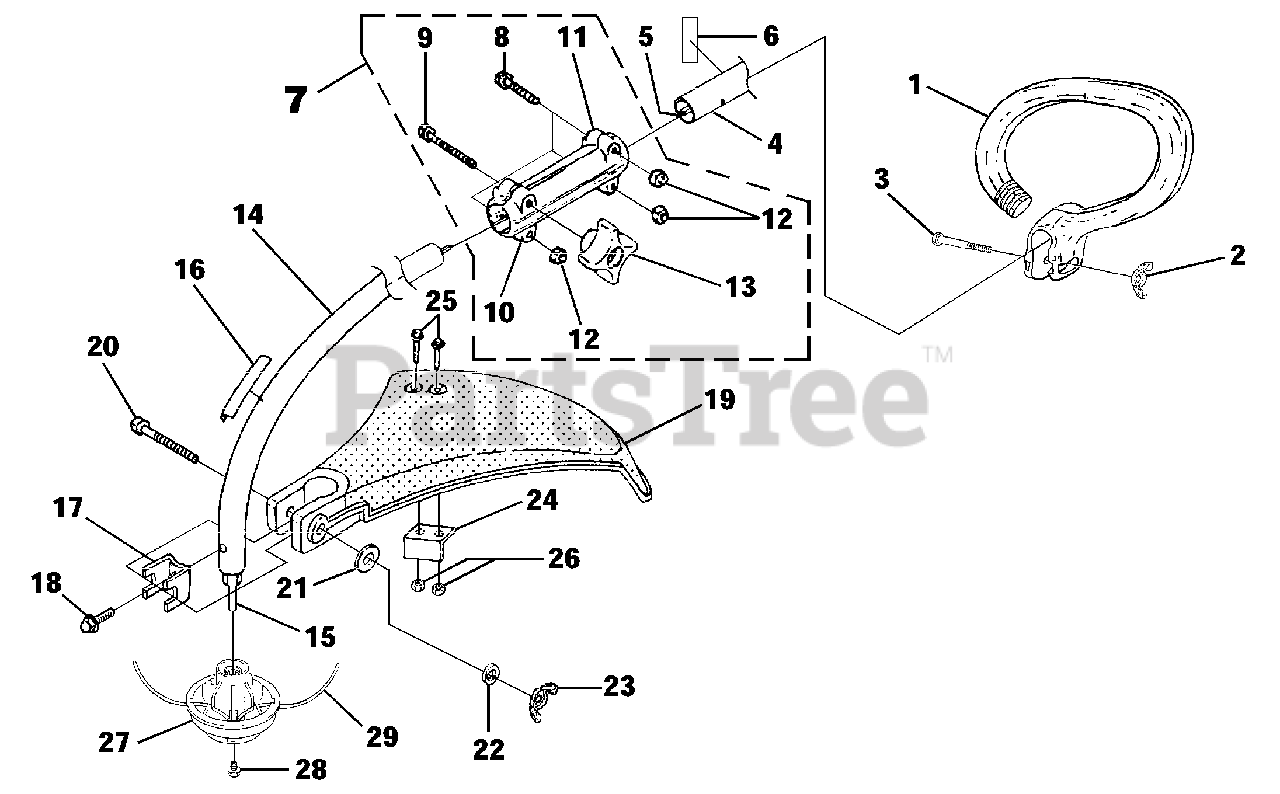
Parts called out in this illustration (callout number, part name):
1	HANDLE-Anti-Vibe
2	NUT-Wing, Washer Faced (1/4-20)
3	SCREW-Cap Hex Hd. (1/4-20 x 2")
4	DRIVESHAFT ASSY. (Upper)
5	FLEXSHAFT w/Collar & Liner
6	DECAL-Warning
7	COUPLER ASSEMBLY
8	SCREW-Hex Hd. (1/4-20 x 1 1/2")
9	SCREW-Cap Hex (1/4-20 x 2")
10	COUPLER (L.H.)
11	COUPLER (R.H.)
12	NUT-Hex (1/4-20)
13	KNOB (1/4-20)
14	DRIVESHAFT HOUSING (Lower)
15	SHAFT-Flex
16	DECAL-Warning
17	CLAMP
18	SCREW-Sems Hex (10-24 X 3/8")
19	DEFLECTOR & BLADE KIT (55 Deg.)
20	SCREW-Cap Hex Hd. (10-24 X 2")
21	WASHER-Flat (1/4")
22	WASHER-Lock (1/4")
23	NUT-Wing, Washer Faced (1/4-20)
24	BLADE-Cut-Off
25	SCREW-Mech. Hex Hd. (10-24 X 7/8")
26	NUT-Hex (10-24)
27	STRINGHEAD-Pro-Cut w/line
28	SCREW-Stringhead Retainer
29	LINE-Replacement
